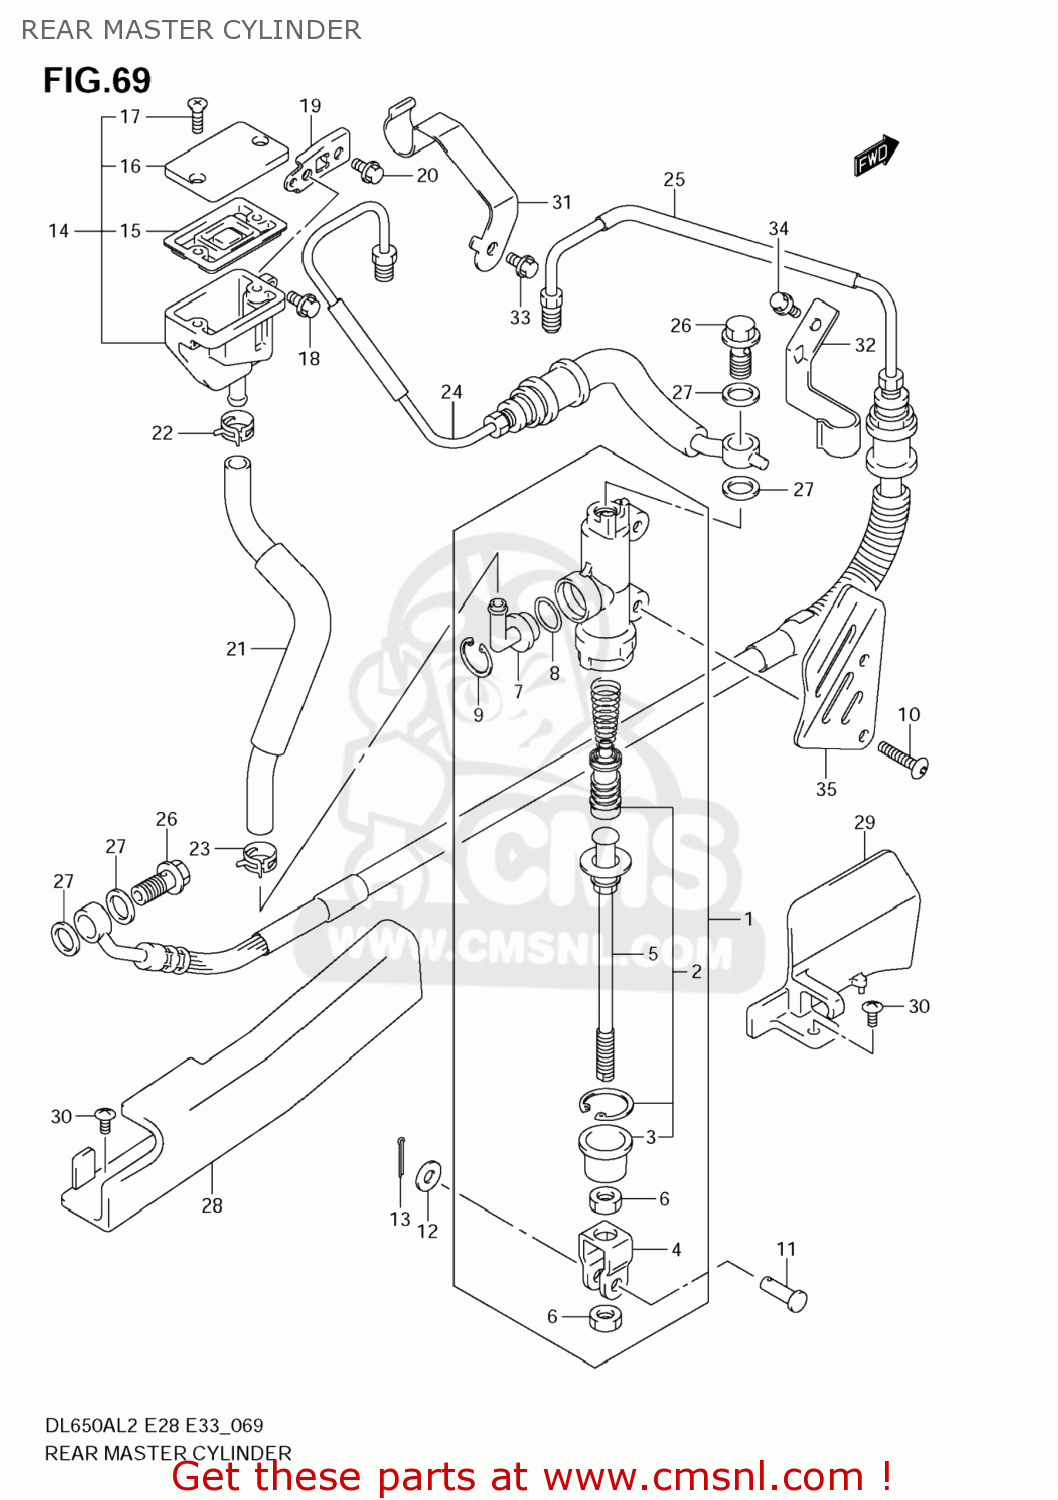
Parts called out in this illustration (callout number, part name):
1	CYLINDER ASSY,RR MASTER
2	PISTON/CUP SET
3	BOOT
4	YOKE
5	ROD,PUSH
6	NUT
7	CONNECTOR
8	O RING
9	CIRCLIP
10	SCREW(6X25)
11	PIN(6X18.2)
12	WASHER
13	PIN
14	TANK ASSY,RR RESERVOIR
15	DIAPHRAGM
16	CAP
17	SCREW
18	BOLT
19	BRACKET,RR RESERVOIR TANK
20	BOLT
21	HOSE,RR RESERVOIR TANK
22	CLIP
23	CLIP
24	HOSE ASSY,RR BRAKE NO.1
25	HOSE ASSY,RR BRAKE NO.2
26	BOLT UNION
27	WASHER(10X15X1.5)
28	GUIDE,RR BRAKE HOSE
29	GUIDE,RR BRAKE HOSE FR
30	SCREW
31	CLAMP,RR BRAKE HOSE
32	CLAMP,RR BRAKE HOSE NO.2
33	BOLT
34	BOLT
35	COVER,RR MASTER CYLINDER
